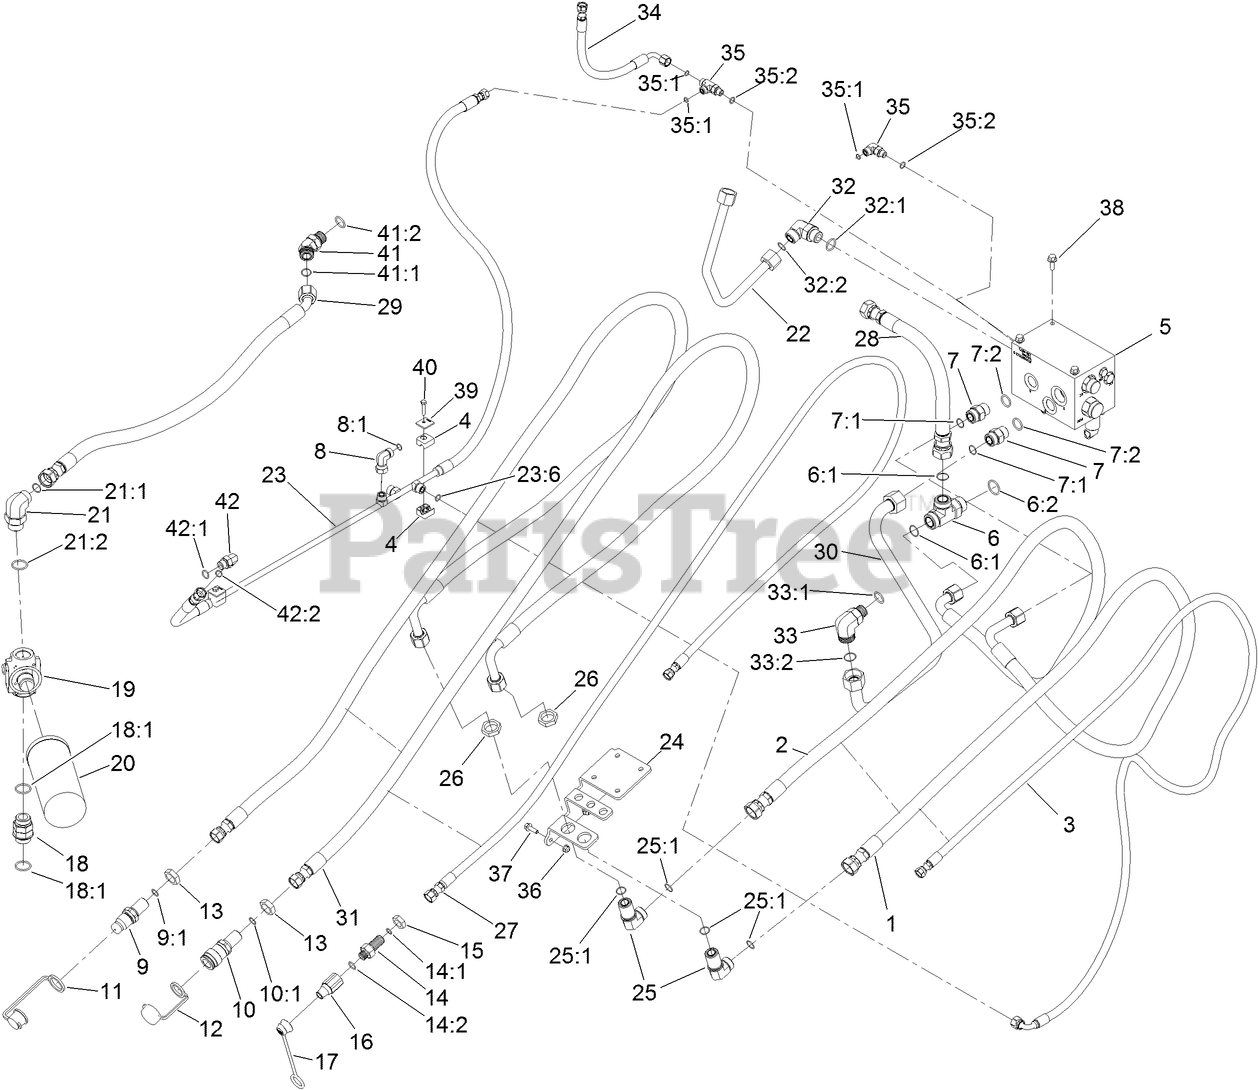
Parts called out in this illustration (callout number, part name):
1	HYD HOSE ASM
2	HYD HOSE ASM
3	HYD HOSE ASM
4	CLAMP-TUBE
5	AUX MANIFOLD ASM
6	FITTING-TEE
6:1	O-RING
6:2	O-RING
7	FITTING-HYD, STRAIGHT
7:1	O-RING
7:2	O-RING
8	FITTING-HYD
8:1	O-RING
9	BULKHEAD NIPPLE ASM
9:1	O-RING
10	BULKHEAD COUPLER ASM
10:1	O-RING
11	CAP-DUST, NIPPLE
12	CAP-DUST, COUPLER
13	NUT-LOCK, BULKHEAD
14	UNION-BULKHEAD
14:1	O-RING
14:2	O-RING
15	NUT-BULKHEAD
16	FITTING-QUICK COUPLING
17	CAP-DUST, NIPPLE
18	FITTING-STRAIGHT
18:1	O-RING
19	HEAD-FILTER
20	ELEMENT-FILTER
21	FITTING-ELBOW 90
21:1	O-RING
21:2	O-RING
22	HYD TUBE ASM
23	HYD TUBE ASM
23:6	O-RING
24	MOUNT-CARRIER
25	FITTING-ELBOW 90
25:1	O-RING
26	NUT-BULKHEAD
27	HYD HOSE ASM
28	HYD HOSE ASM
29	HYD HOSE ASM
30	HYDRAULIC TUBE ASM
31	HYD HOSE ASM
32	FITTING-ELBOW-90
32:1	O-RING
32:2	O-RING
33	FITTING-ELBOW 90
33:1	O-RING
33:2	O-RING
34	HYD HOSE ASM
35	FITTING-TEE
35:1	O-RING
35:2	O-RING
36	NUT-HF, NI
37	SCREW-HHF
38	SCREW-HHF
39	PLATE-CLAMP,TUBE
40	SCREW-HH
41	FITTING-45 DEG
41:1	O-RING
41:2	O-RING
42	FITTING-ELBOW, 90 DEG
42:1	O-RING
42:2	O-RING
